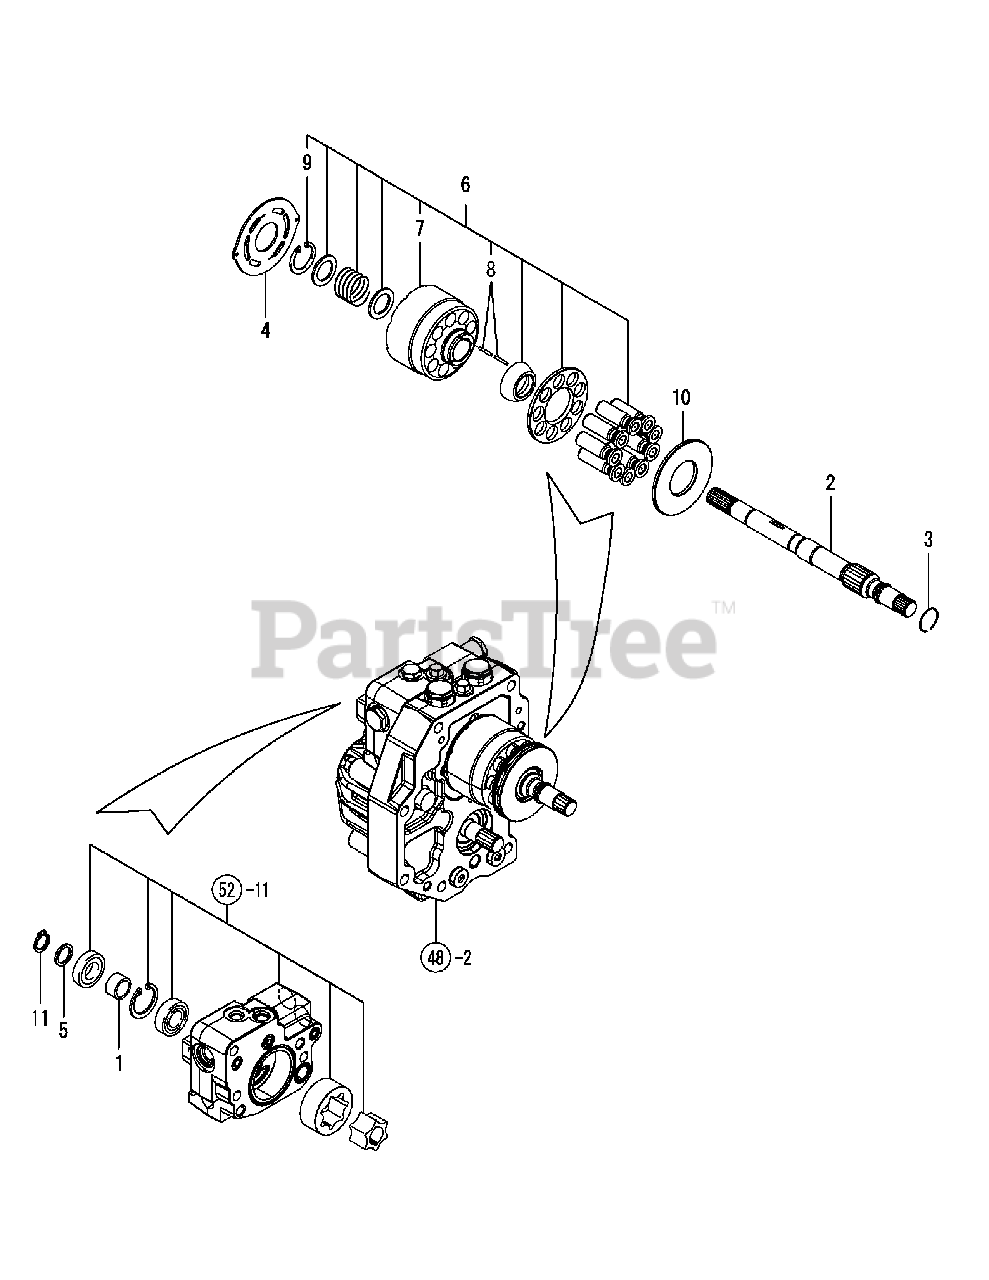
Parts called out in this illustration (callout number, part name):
1	Sleeve 17X22X12
6	Block Assy, Cyl
7	Block, Cylinder
